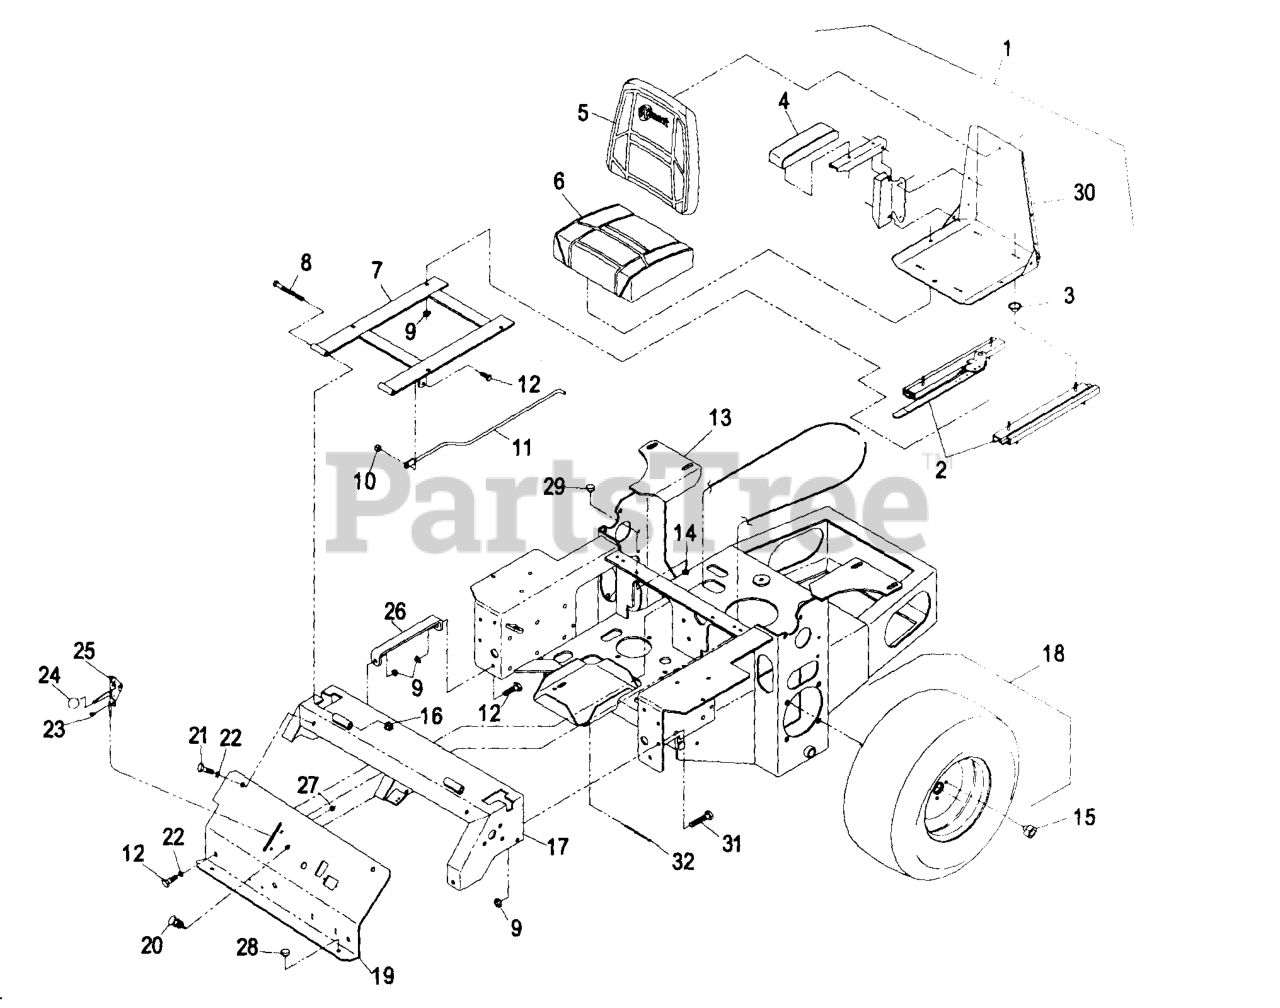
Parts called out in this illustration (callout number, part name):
3	SPACER-TRACK
13	Frame, Engine Deck
18	WHEEL AND TIRE ASM
20	CONTROL-CHOKE
23	BOLT-CARR
24	KNOB-BALL
25	THROTTLE CABLE ASM
30	FRAME-SEAT
32	TIE-PLASTIC
